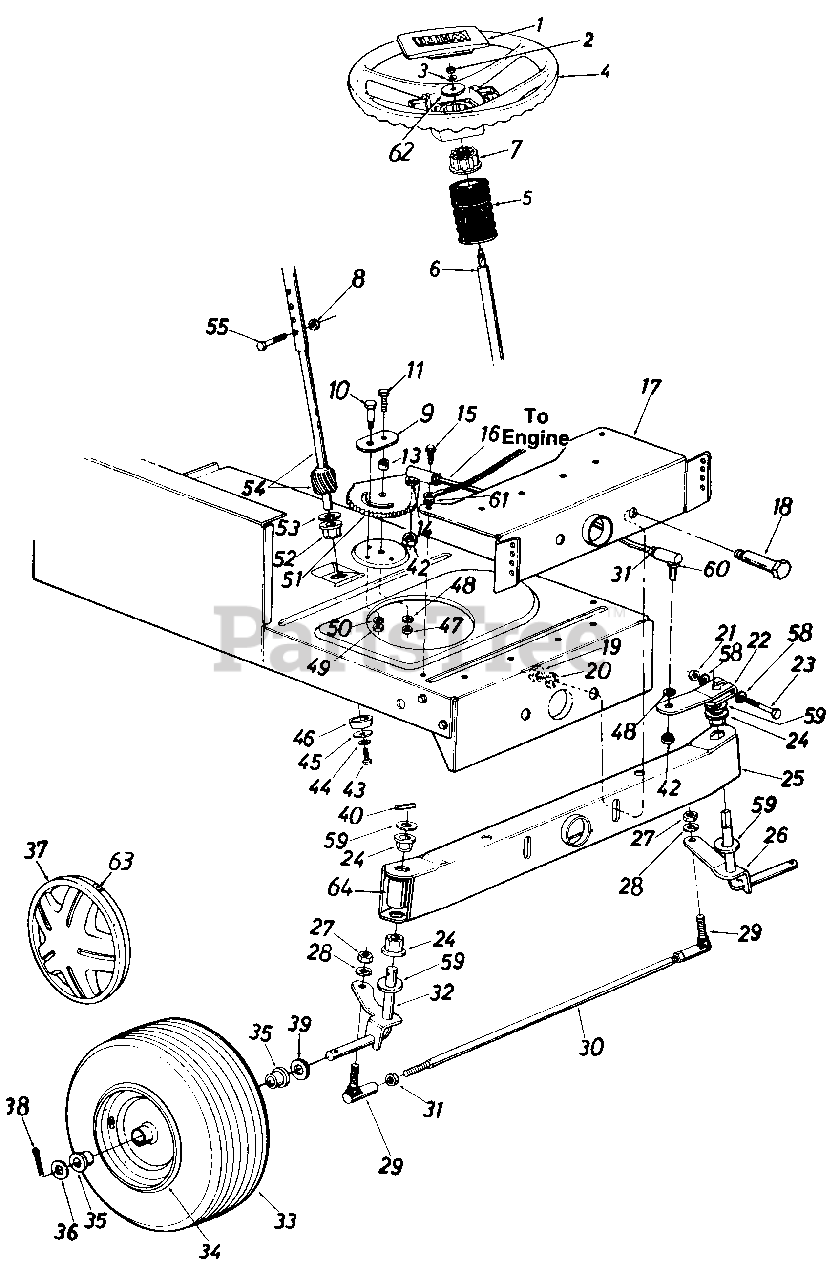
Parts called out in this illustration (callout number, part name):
1	Steering Wheel Insert
2	Hex L-Nut 5/16-24 Thd.
3	Belleville Wash. .345" I.D.
4	Steering Wheel
5	Steering Bellow
6	Steering Column Ass'y.
7	Steering Wheel Adapter
8	Hex Nut 1/4-20 Thd.
9	Retainer Plate
10	Shoulder Bclt .437" Dia. x .35" Lg. 5/16-1& Thd.
11	Hex Bolt 3/8-24 x 1.0" Lg. (Grade 5)
13	Spacer .380" I.D. x .625" O.D. x .227"
14	L-Wash. 3/8" I.D.
15	Hex Wash. Hd. Self-Tap Scr.
16	Steering Drag Link
17	Front Pivot Brkt.
18	Shoulder Bolt .498" Dia. x 2 04" Lg. 3/8-16 Thd.
19	Hex Nut 3/8-16 Thd.
20	L-Wash. 3/8" I.D.
21	Hex Cent. L-Nut 5/16-24 Thd.
22	Steering Arm Front Axle
23	Hex Bolt 5/16-24 x 2.00" Lg. (Grade 5)
24	Hex Flg. Brg. .634" I.D.
26	Front Axle Ass'y.-L.H.
27	Hex Nut 3/8-24 Thd.
28	L-Wash. 318" I.D.
29	Ball Joint 3/8-24 Thd.
31	Hex Jam Nut 3/8-24 Thd.
32	Front Axle Ass'y.-R.H.
33	Wheel Ass'y. Comp.
34	Front Wheel Rim Only
35	Flange Bearing
36	Fl-Wash. .635" I.D. x 1.59" O.D.
38	Cotter Pin 1/8" Dia. x 1.25" Lg.
39	Fl-Wash. .640" I.D. x .24" O.D.
40	Spring Roll Pin
42	Hex Jam Nut 3/8-24 Thd.
43	Hex L-Bolt 5/16-18 x .62"t
44	L-Wash. 5/16" l.D.
45	Fl-Wash. .33" l.D. x 1.25" O.D.
46	Spacer (Plastic)
47	Hex Nut 3/8-24 Thd.
48	L-Wash. 3/8" l.D.
49	Hex Nut 5/16-18 Thd.
50	L-Wash. 5/16" I.D.
51	Steering Gear Segment
52	Hex Flg. Brg. .634 I.D.
53	Fl-Wash. (Hardened)
54	Steering Shatt Lower
55	Hex Bolt 1/4-20 x 1.31" Lg.
58	Wave Wash. .32" I.D. x .62"
59	Fl-Wash. (Hardened)
60	Drag Link Ball Joint 3/8-24 Thd.
61	Ext. L-Wash. 5/16" l.D.
62	Fl-Washer
63	Spring Clip
64	Plastic Tube
